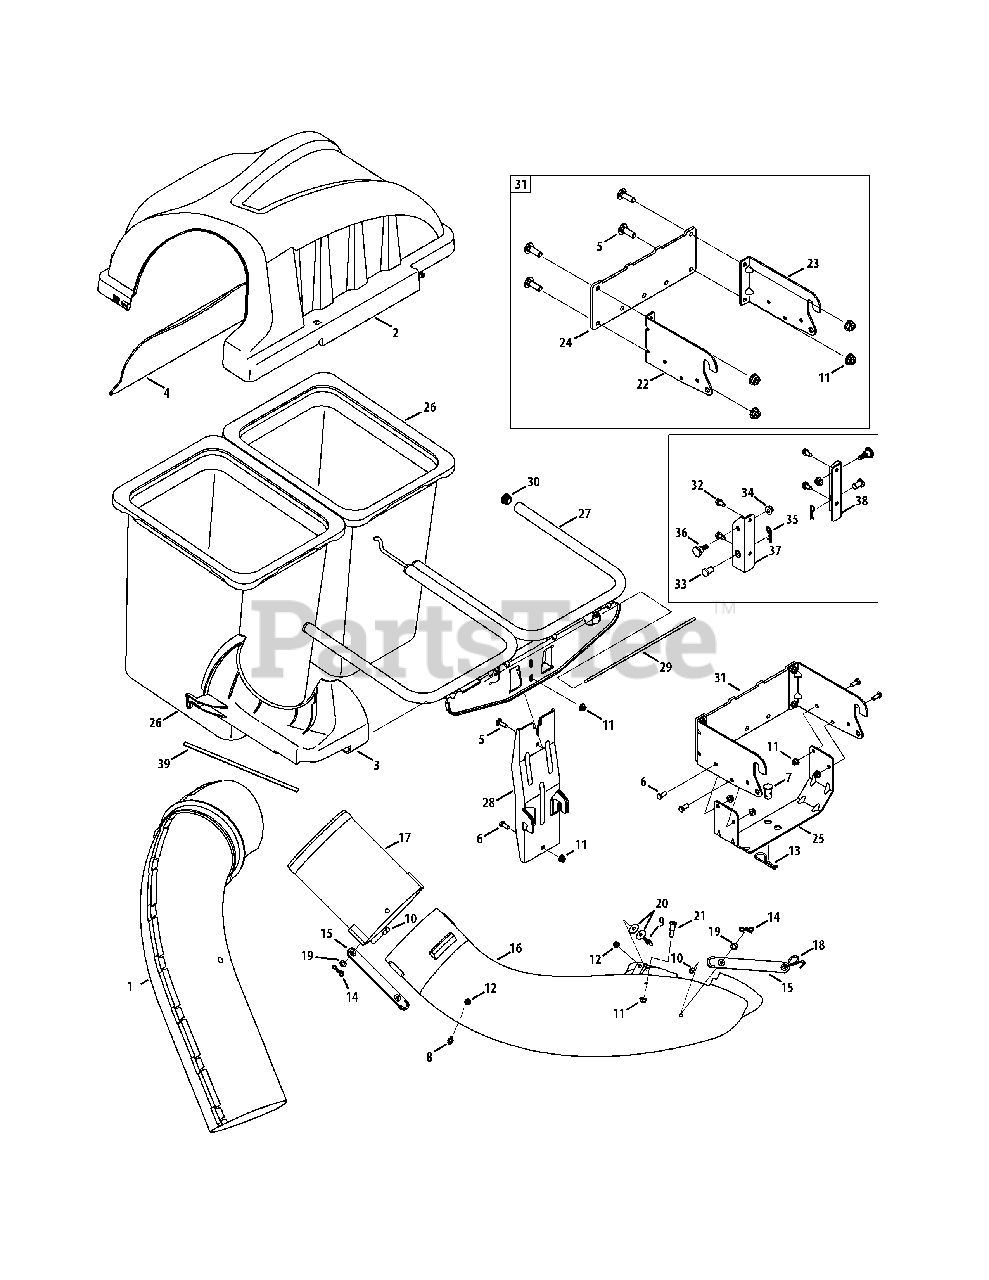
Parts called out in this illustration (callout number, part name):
1	Upper Chute Assembly
2	Double Bagger Cover Assembly
3	Upper Chute Support
4	Bagger Cover Screen
5	Carriage Screw, 5/16-18 x 1.00"
6	Hex Head Screw, 5/16-18 x .75"
7	Clevis Pin, .62" Dia.
8	Grass-catcher Pin, 1/4-20
9	Attachment Pin, 1/4 x 0.66 Lg.
10	Clevis Pin, 5/16 x .75 Lg.
11	Flange Lock Nut, 5/16-18
12	Flange Lock Nut, 1/4-20
13	Internal Cotter Pin, .148 x 3.00
14	Bow-Tie Cotter Pin, 72
15	Chute Strap, 6.00 Lg.
16	Bagger Discharge Chute, Elbow
17	Bagger Chute Adapter, 7 In.
18	Torsion Spring Hook
19	Flat Washer, .344 x .62 x .033
20	Flat Washer, .265 x .938 x .120
21	Shoulder Screw, .437 x .54
22	Mounting Bracket, RH
23	Mounting Bracket, LH
24	Universal Mounting Bracket
26	Grass-bag Assembly
27	Double Bag Support Assembly
28	Vertical Support Bracket
29	Cover Hinge Pin
30	End Plug
31	Mounting Bracket Assembly Kit (Incl. ref. 22, 23, 24)
32	Tap Screw, 5/16-18 x .750
33	Clevis Pin, .50 x .78
34	Flange Lock Nut, 3/8-16
35	Click Pin, .092 x 1.64 Lg.
36	Shoulder Screw, .625 x .412
37	Mounting Bracket, RH
38	Mounting Bracket, LH
39	Self-Adhesive Foam Strip
